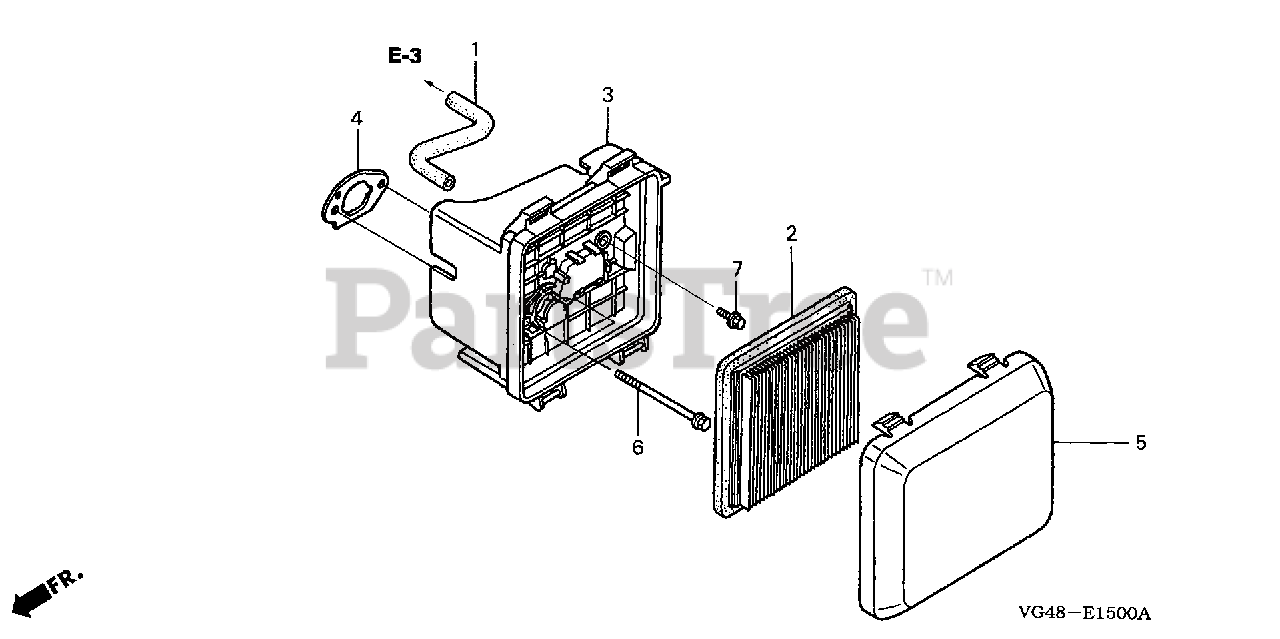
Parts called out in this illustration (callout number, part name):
1	TUBE, BREATHER
2	ELEMENT, AIR CLEANER
2	ELEMENT, AIR CLEANER (TOYO ROKI)
3	CASE ASSY., AIR CLEANER
4	GASKET, AIR CLEANER
5	COVER, AIR CLEANER
6	BOLT, FLANGE (6X86) (CT200)
7	BOLT, FLANGE (6X14)
